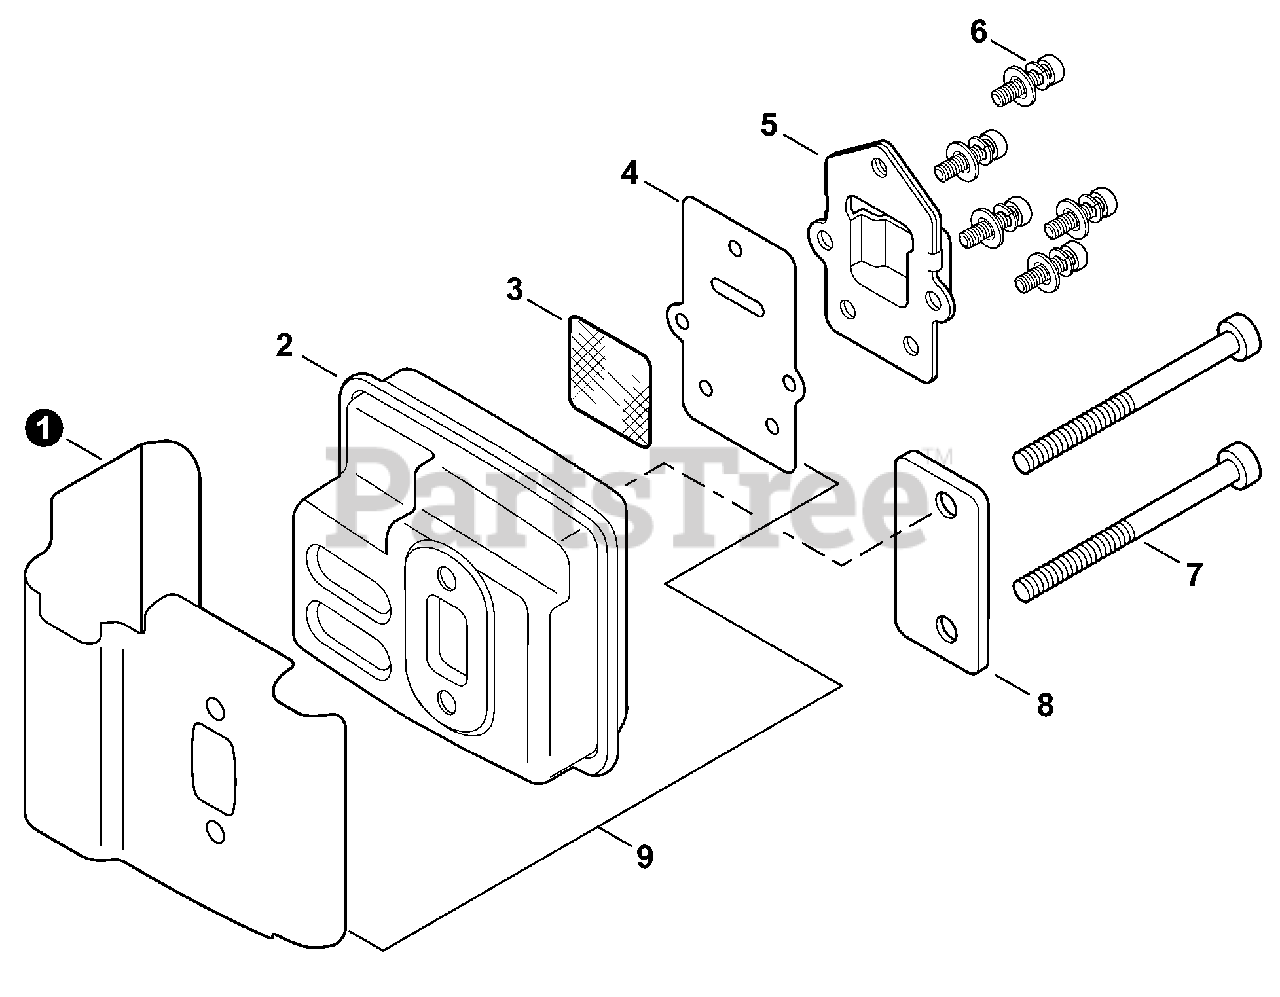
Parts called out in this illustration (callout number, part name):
1	HEAT SHIELD, EXHAUST
2	MUFFLER
3	SCREEN, SPARK ARRESTER
4	GASKET, EXHAUST
5	GUIDE, EXHAUST
6	SCREW 4×10
7	BOLT 5×55
8	PLATE, EYE
9	GASKET KIT
